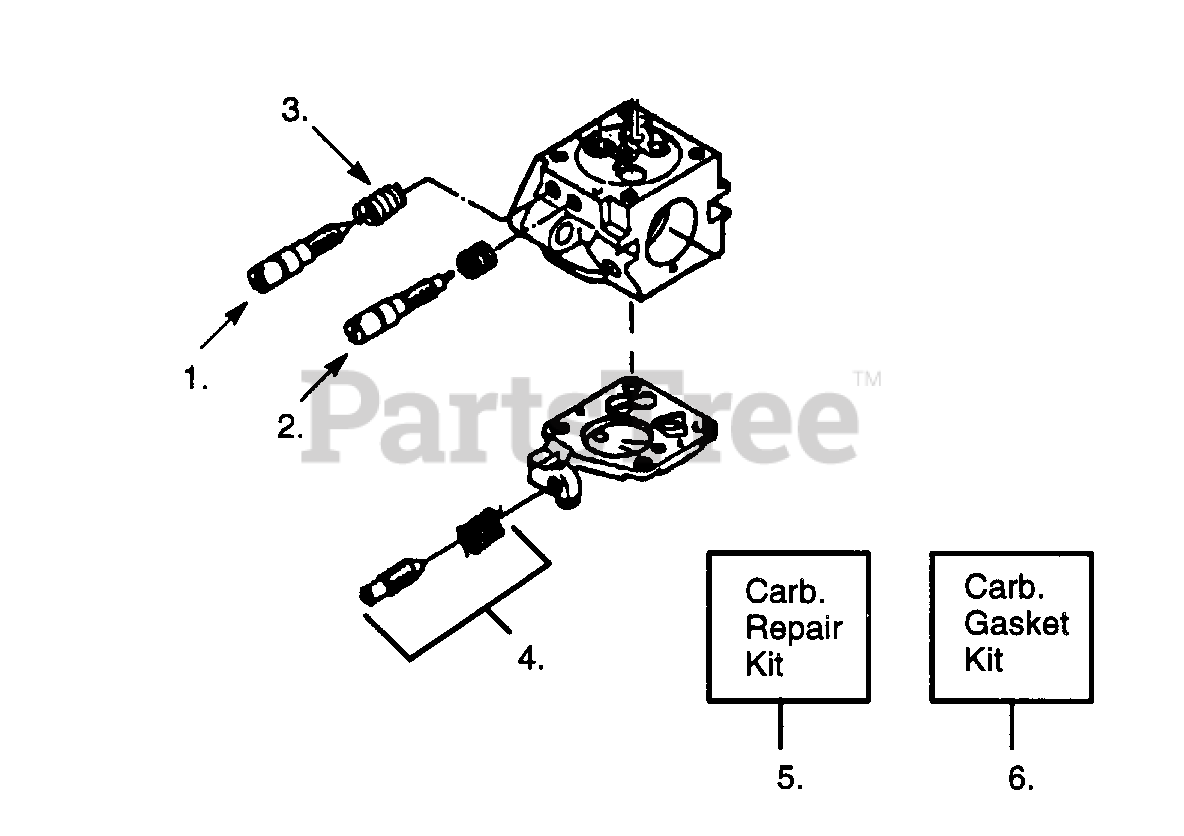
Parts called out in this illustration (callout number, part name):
1	Idle Low Mixture Screw
2	High Mixture Screw
3	Low/High Mixture Screw Spring
4	Pump Cover Kit
6	Gasket/Diaphragm Kit
